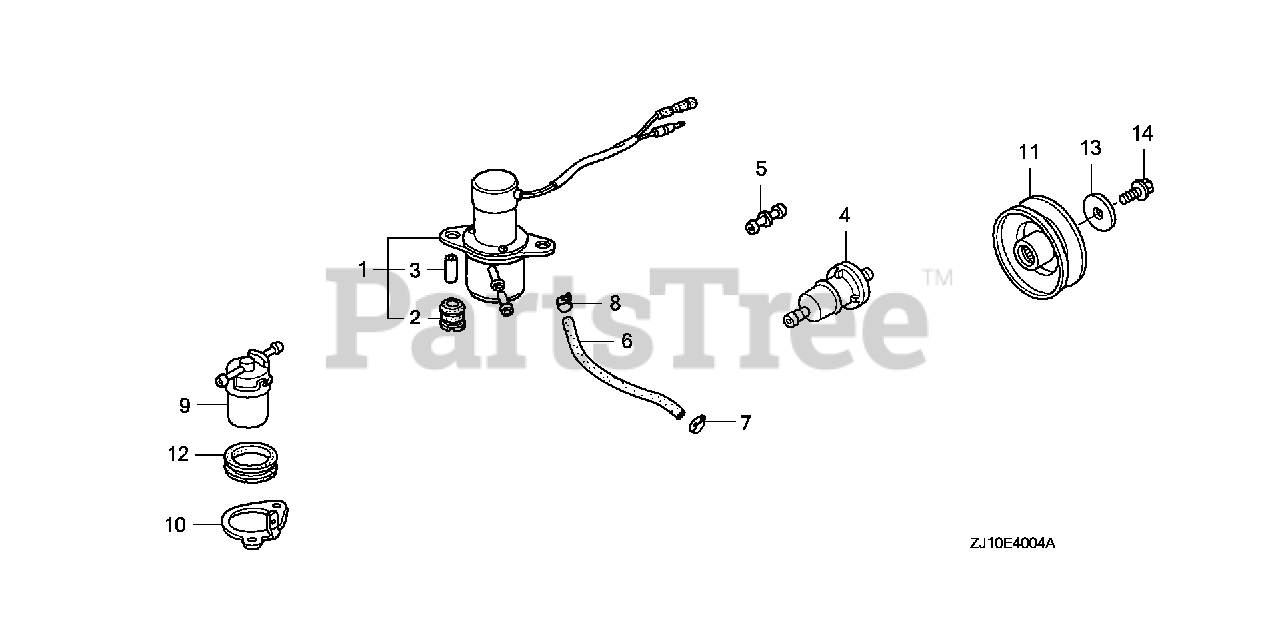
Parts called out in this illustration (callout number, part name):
1	PUMP ASSY., FUEL (MSDS)
2	RUBBER, FUEL PUMP MOUNTING
3	COLLAR, DISTANCE
4	FILTER, FUEL
5	JOINT, FUEL TUBE
6	TUBE, FUEL SPECIAL
7	CLAMP, TUBE (D8)
8	CLAMP, TUBE (D8.5)
